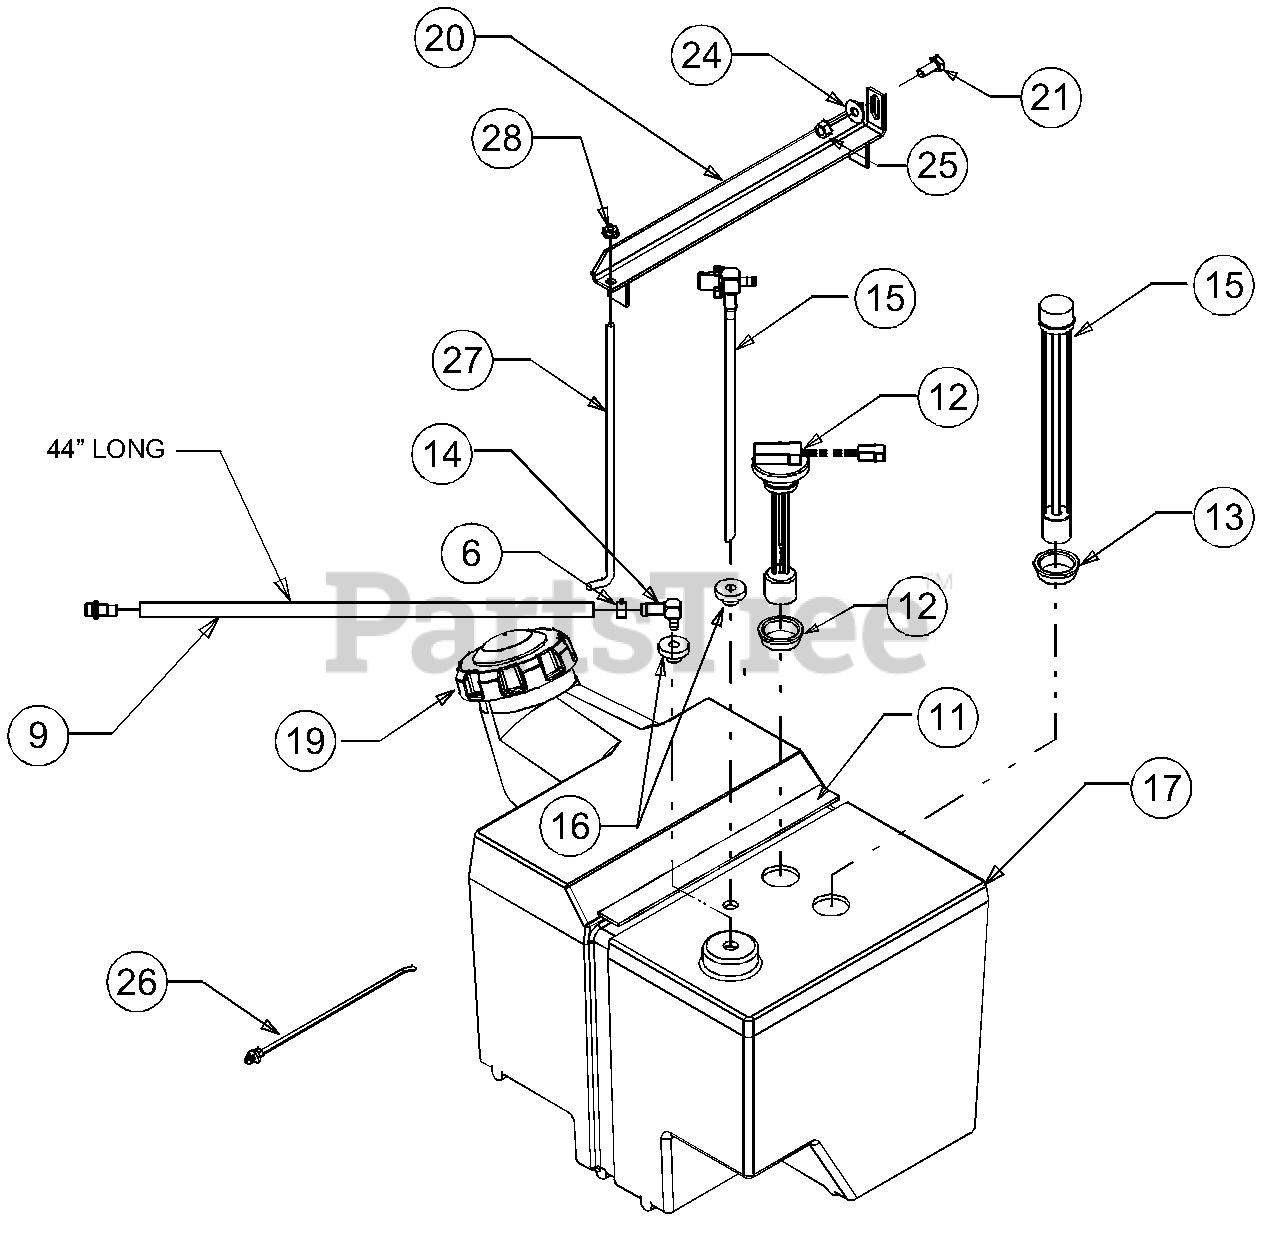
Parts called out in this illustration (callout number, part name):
6	Clamp, Hose
9	Hose, Fuel Line
11	Gasket, Fuel Tank, 11.5
12	Switch, Fuel Level Gauge
13	Grommet, 1.58 OD x 1.21 ID x .5
14	Fitting, Elbow, .190 ID
15	Valve, Fuel Tank
16	Grommet, 1.06 OD x .362
17	Tank, Fuel
18	Gauge, Fuel Tank
19	Cap, Fuel, 3.5
20	Bracket Assembly, Fuel Tank
21	Hex Screw, 5/16-18 x .75
24	Washer, .349 x .879 x .063
25	Sems Nut, 5/16-18
26	Cable Tie, Tree Mount
27	Hold-down Rod, Fuel Tank
28	Nut, Flange Lock, 1/4-20
